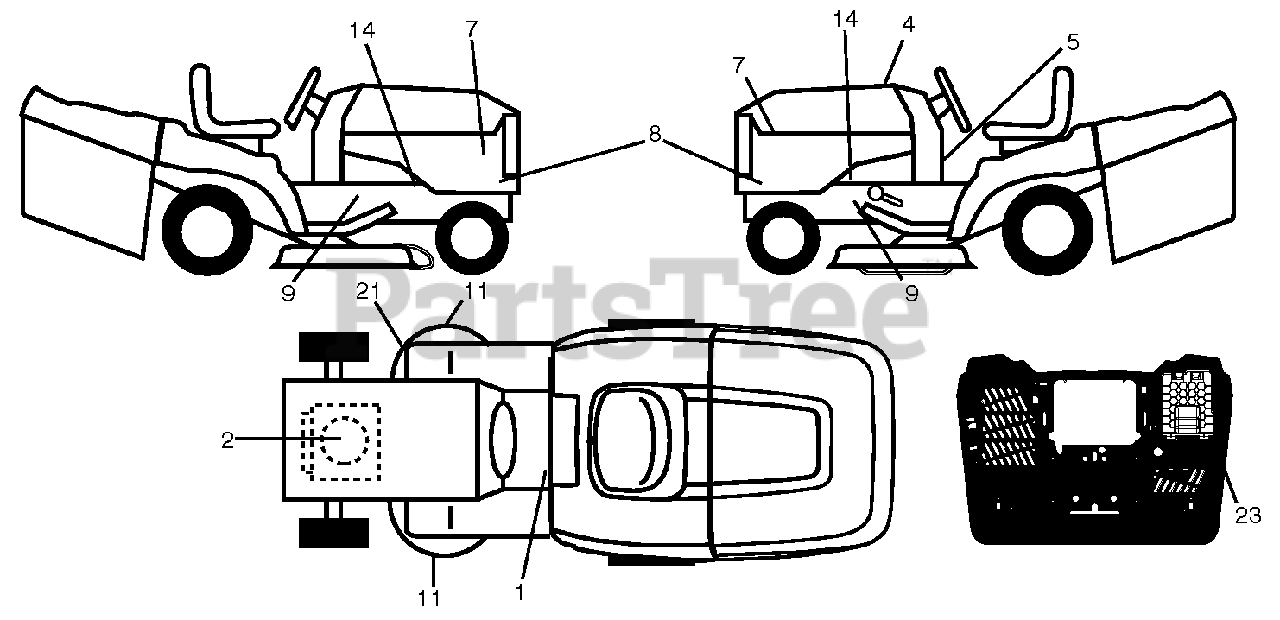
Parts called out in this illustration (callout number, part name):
1	DECAL.WARNING.COMBINED.T/CRD
2	DECAL.ENGINE.WARNING
4	DECAL.RPL.FS.TCRD.97.K46
7	DECAL.BADGE.170MM.TEXTLOGO.
9	DECAL.WARNING.SERVCE/FIRE
11	DECAL.CUTFINGER.CE.02
14	DECAL.CHASSIS.HOT.MUFFLER
21	DECAL DECAL V-BELT 97 CM CRD
23	DECAL DECAL.BYPASS.BACKPLATESI
